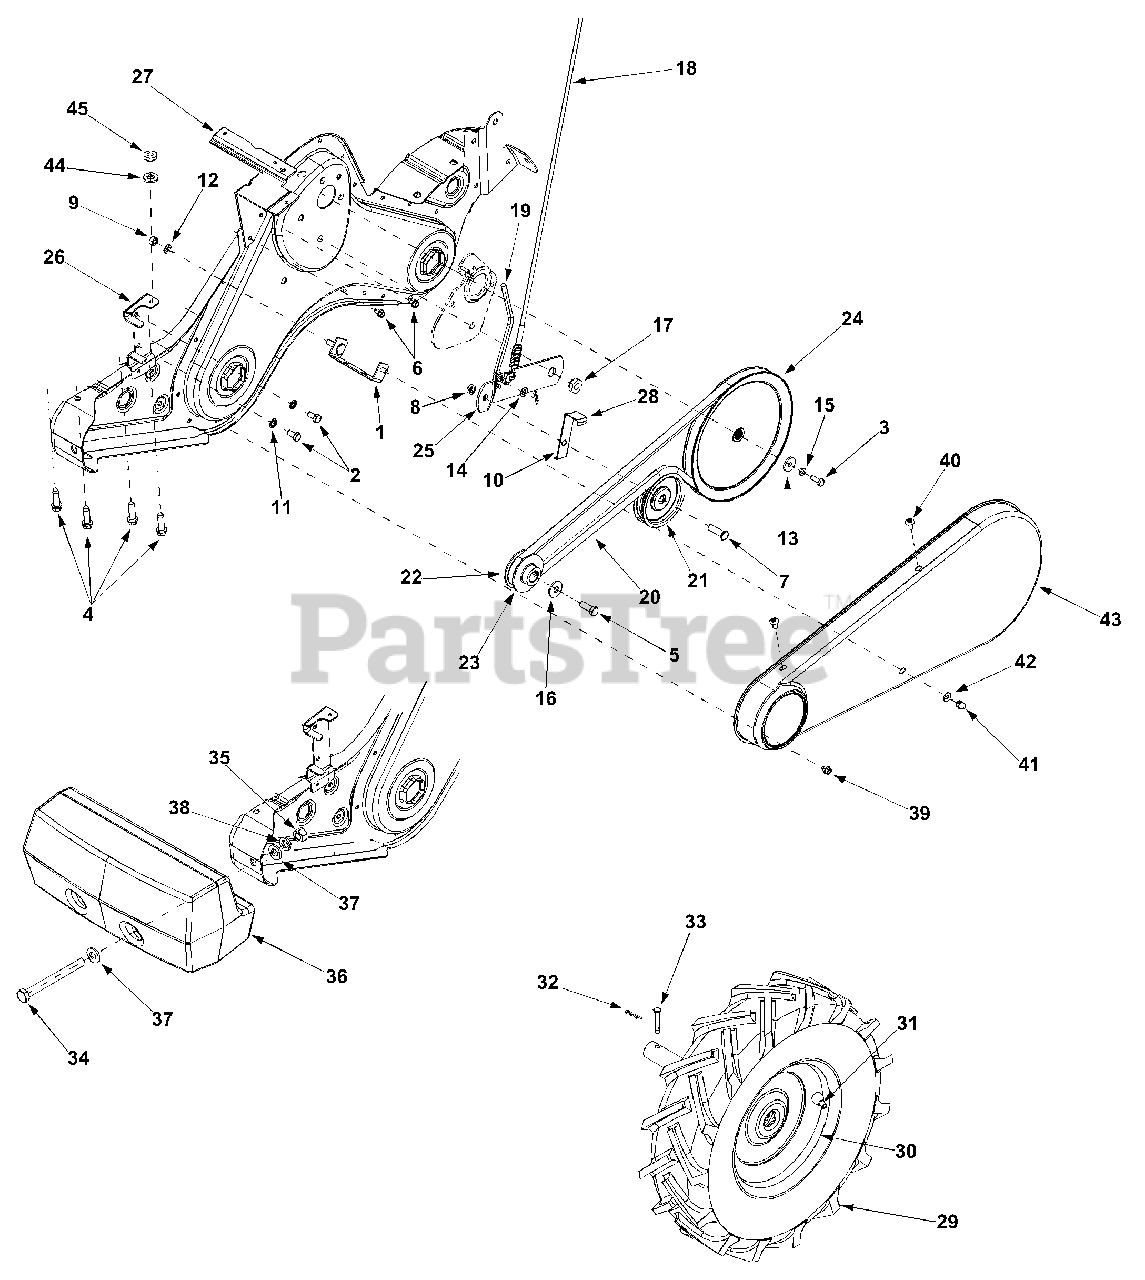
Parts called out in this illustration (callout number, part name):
2	Hex Bolt 5/16-24 x .62"
3	Hex Bolt 1/4-28 x .75"
4	Hex Washer Screw 3/8-16 x 1.25"
5	Hex Bolt 3/8-24 x 1.0
6	Hex Washer Screw
7	Hex Cap Screw 3/8-16 x 1.25
8	Lock Jam Nut 3/8-16
9	Hex Nut 5/16-18
10	Internal Cotter Pin
11	Hairpin Clip
12	Lock Washer 5/16"
13	Flat Washer .25 ID x .93 OD
14	Spring Washer .317 ID x .625 OD
15	Lock Washer 1/4" ID
16	Bell Washer .396 ID x 1.14 OD
17	Shoulder Nut 7/16-20
18	Clutch Cable
19	Idler Pulley Rod
20	V-Belt
21	Flat Idler w/Flange 3.75 OD
22	Outer Engine Pulley Half
23	Inner Engine Pulley Half
24	Input Pulley
25	Idler Bracket
26	Belt Keeper Bracket
29	Wheel Assembly RH 14.0 x 4.5
32	Clevis Pin
33	Internal Cotter Pin
34	Hex Bolt 1/2-13 x 5.0
35	Hex Nut 1/2-13
36	Counterweight
37	Flat Washer .510 ID x 1.0 OD
38	Lock Washer 1/2
39	Hex Screw 1/4-20 x .375
40	Screw 1/4-14 x .625
41	Lock Nut
42	Flat Washer .271 ID x .630 OD
44	Bell Washer .340 ID x .872 OD
45	Hex Nut 5/16-18
